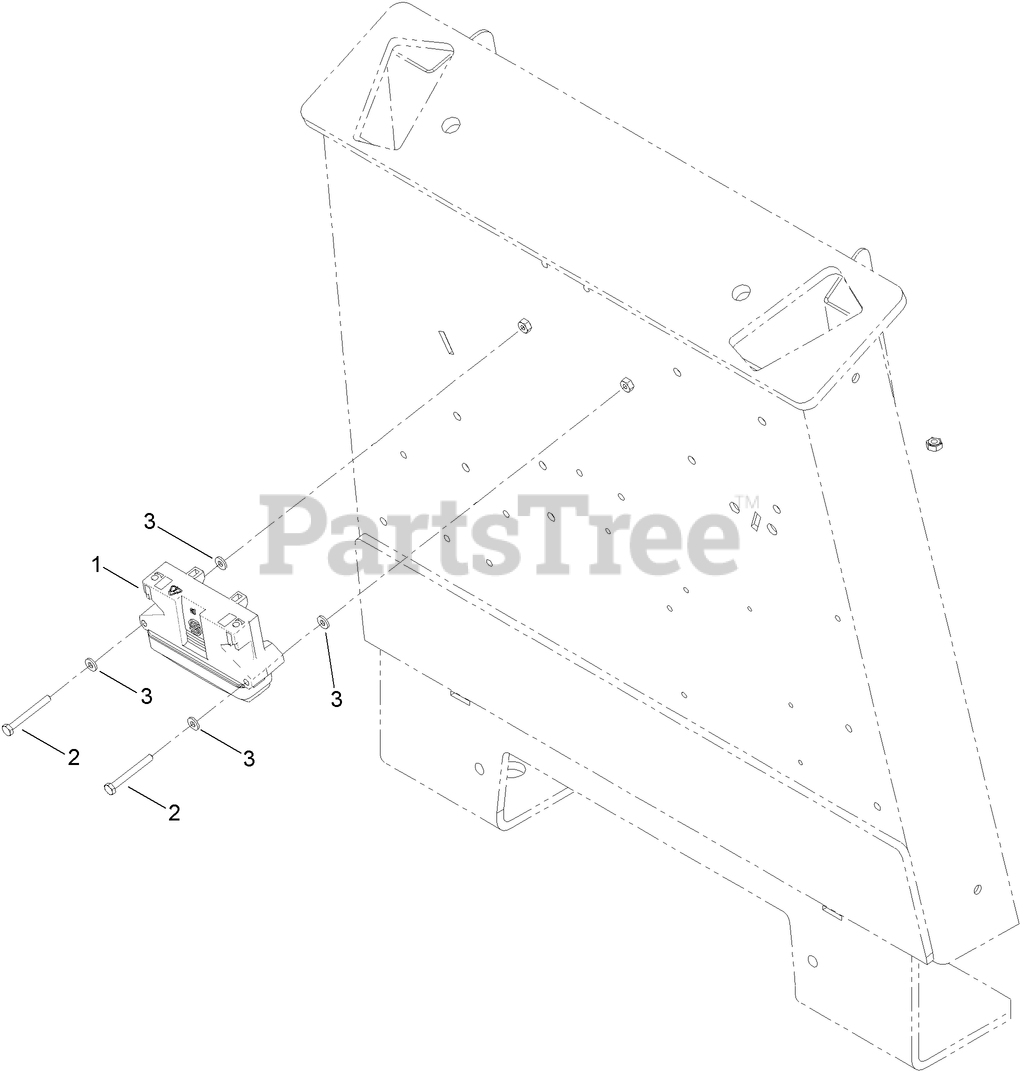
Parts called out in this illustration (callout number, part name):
1	COMPUTER-EXPANDER, OUTPUT
2	SCREW-HH
3	WASHER-FLAT
